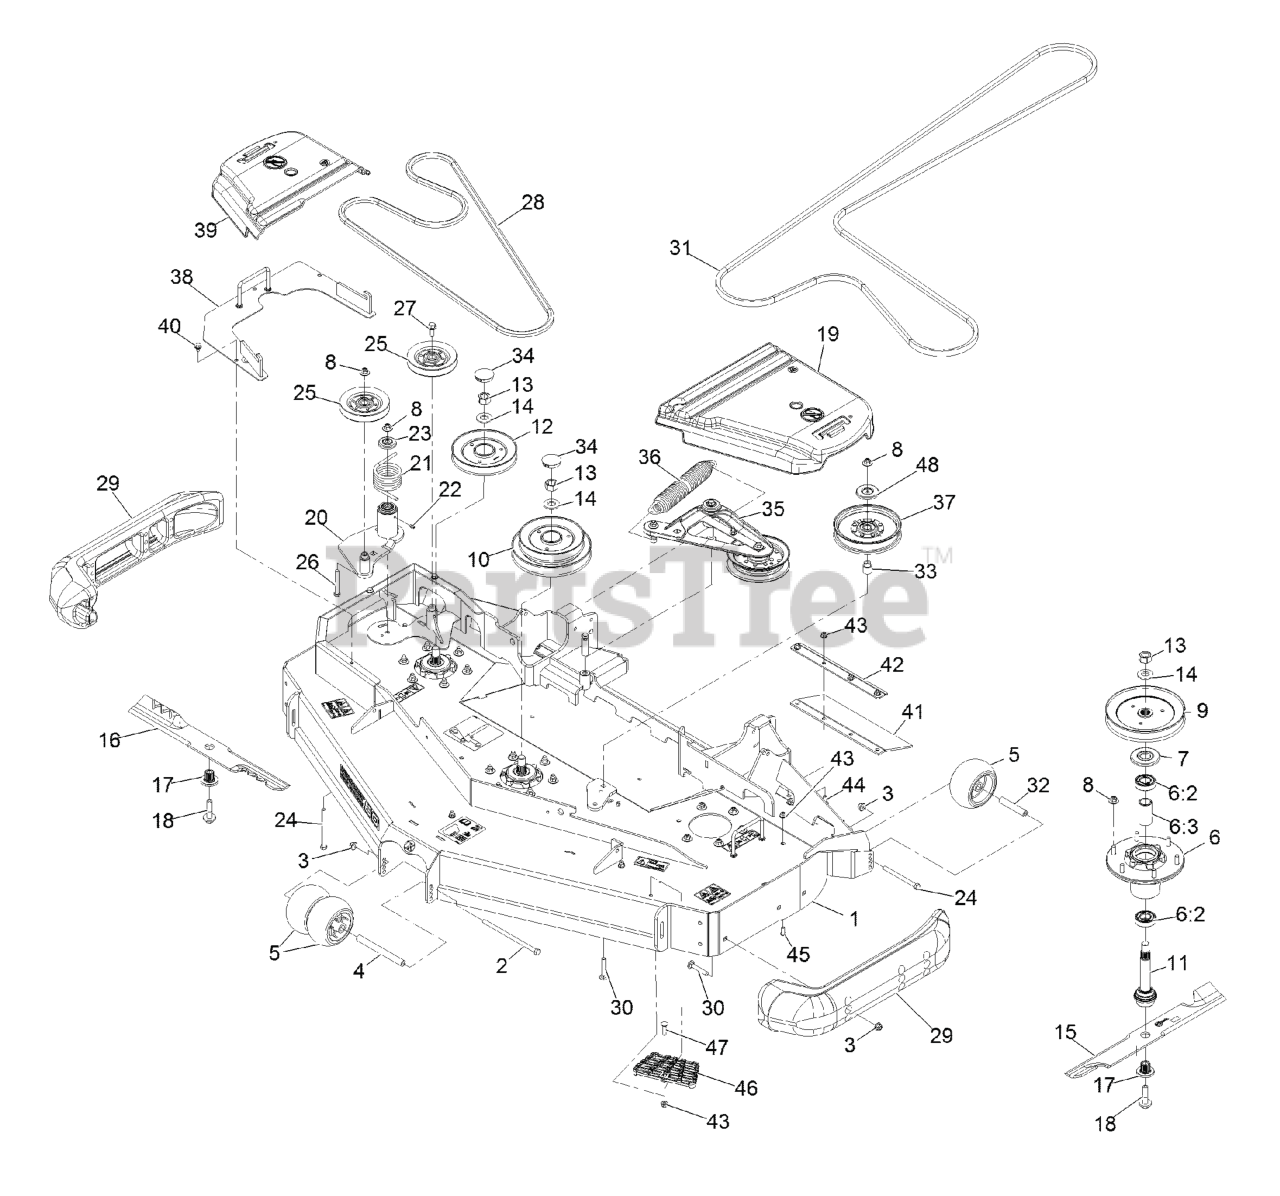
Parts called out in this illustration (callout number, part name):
1	DECK-RD60 NLZ, W/DECALS
2	SCREW-HH
3	NUT-HF, NI
4	SPACER-WHEEL
5	ROLLER-SCALP, ANTI
6	ASM-CUTTER HSG WITH BEARINGS
6:2	BEARING-BALL
6:3	SPACER-BEARING
7	GUARD,BEARING TOP .989
8	Nut-Nyloc 3/8-16 Flg
9	SHEAVE,BLADE DRIVE 7.25
10	SHEAVE, DOUBLE 60RD
11	ASM-SPINDLE AND SEAL
12	SHEAVE-RD REV DRIVE SERIES 4
13	NUT-HEX
15	Blade-Extreme 2, 20.50"
16	Blade-Low Lift 20.5, Rd60
16	Blade-Extreme 2-20.50, Rd60
17	BUSHING,SPLINED
18	SCREW,SEMS 1/2-20 X 2.19
19	COVER-BELT, LH
20	IDLER ASM
21	SPRING-TORSION
22	FITTING-GREASE
23	GUARD-TOP
24	SCREW-HH
26	SCREW-HH
27	SCREW-HHF
28	BELT
29	SKID-BUMPER, DECK
30	Bolt-Carriage 3/8-16 X 2 1/4
31	BELT
32	TUBE-SPANNER
33	BUSHING-IDLER
34	PLUG,BLACK NYLON 1.75
35	DECK IDLER ASM
36	SPRING-EXTENSION
37	IDLER-PULLEY, FLAT 6.00X1.00
38	COVER-DRIVE REVERSE
39	COVER-BELT, RH
41	GUARD-TIRE
42	SUPPORT-OUTER FLAP
43	NUT-HF, NI
44	SCREW-CARR
45	SCREW-HSBH
46	STEP-DECK
47	Bolt-Carriage 5/16-18 X 1 1/4
48	SHIELD-DUST
